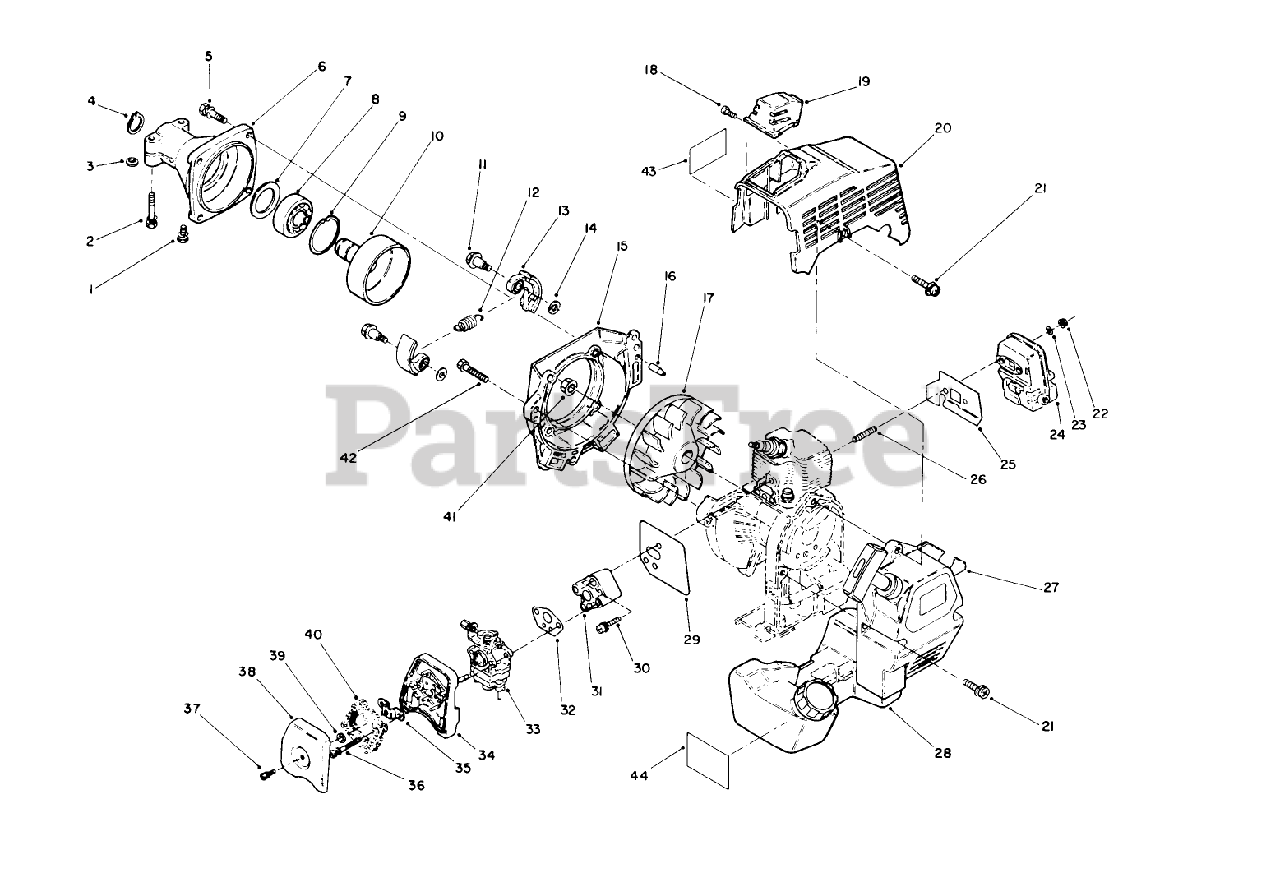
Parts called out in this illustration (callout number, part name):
8	BALL BEARING
10	CLUTCH DRUM
11	CLUTCH BOLT
13	SHOE, CLUTCH
18	SCREW & WASHER
20	TOP COVER
21	SCREW & WASHER
23	GASKET
25	MUFFLER GASKET
30	SCREW & WASHER
31	INSULATOR
32	CARBURETOR GASKET
34	CLEANER CASE
36	SCREW W/ WASHER
37	SCREW & WASHERE
38	CLEANER COVER
40	CLEANER ELEMENT
42	BOLT AND WASHER
43	DECAL-SURFACE, HOT
